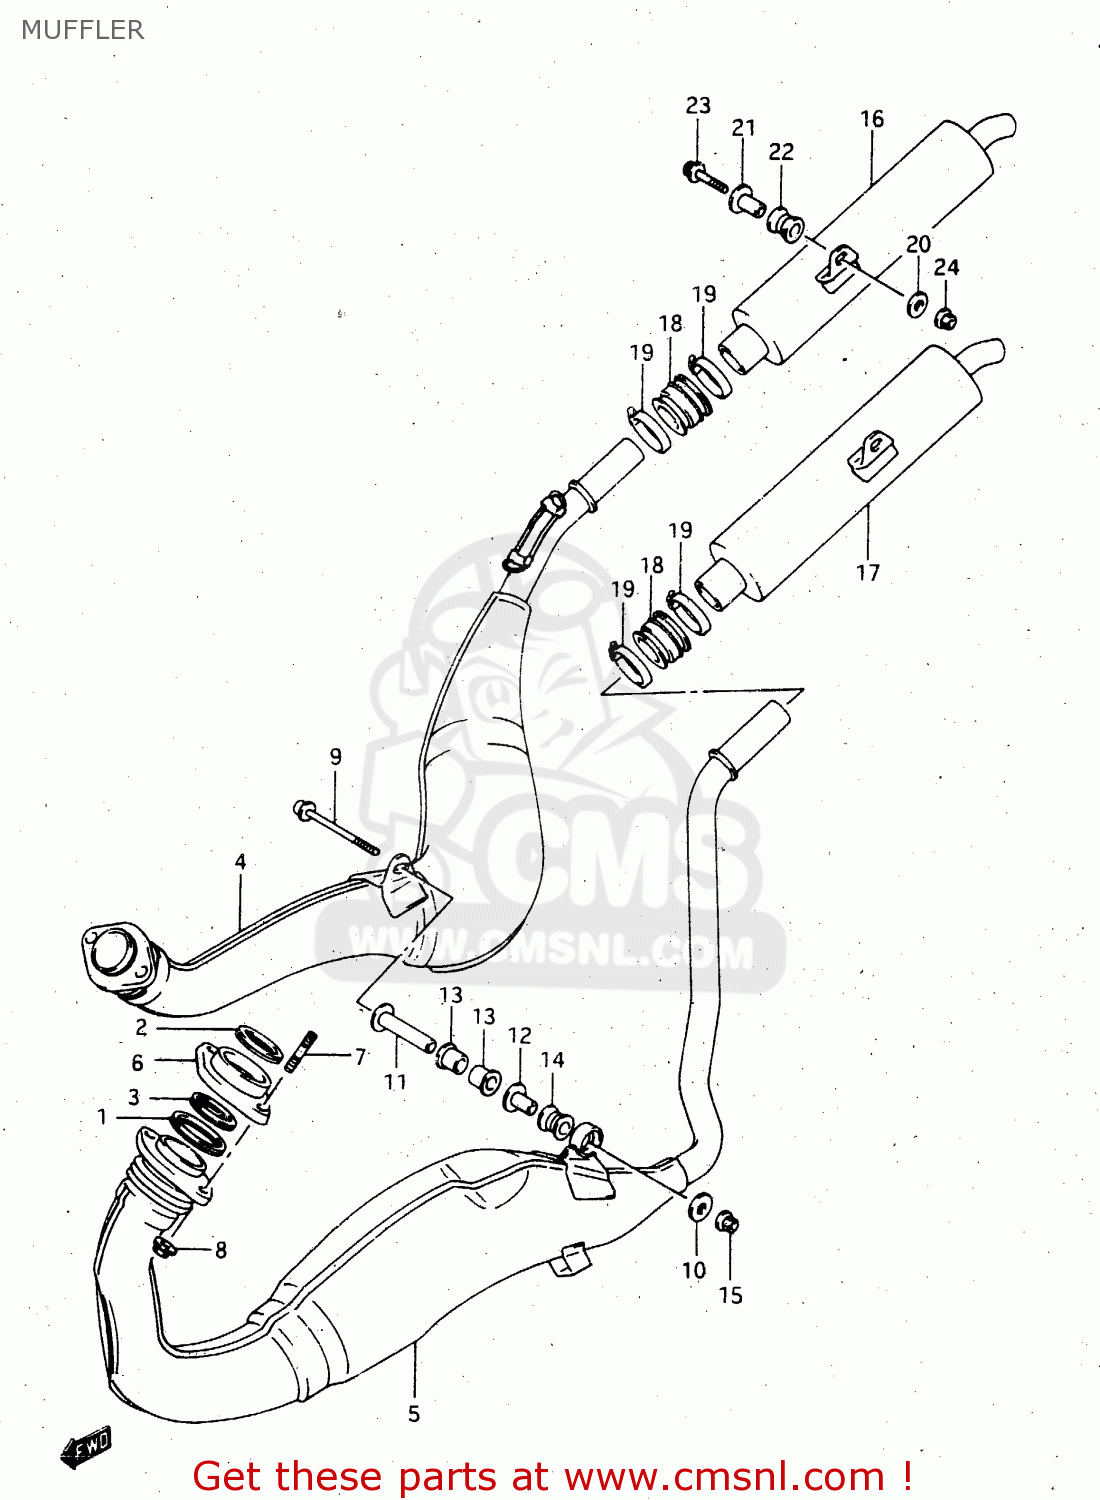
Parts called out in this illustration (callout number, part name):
1	GASKET,EXHAUST PIPE (NAS)
2	GASKET,EXHAUST PIPE (NAS)
3	GASKET,EXHAUST PIPE (NAS)
4	BODY, MUFFLER 1ST RH
5	BODY ,MUFFLER,
6	FLANGE,EXHAUST FITING
7	BOLT,STUD
8	NUT
9	BOLT(8X105)
10	WASHER
11	SPACER,SUPPORT
12	SPACER(8.6X12X17.5)
13	CUSHION
14	CUSHION
15	NUT
16	BODY, MUFFLER 2ND UPPER
17	BODY, MUFFLER 2ND LOWER
18	CONNECTOR,2ND MUFFLER
19	CLAMP
20	WASHER
21	SPACER(8.6X12X17.5)
22	CUSHION
23	BOLT
24	NUT
